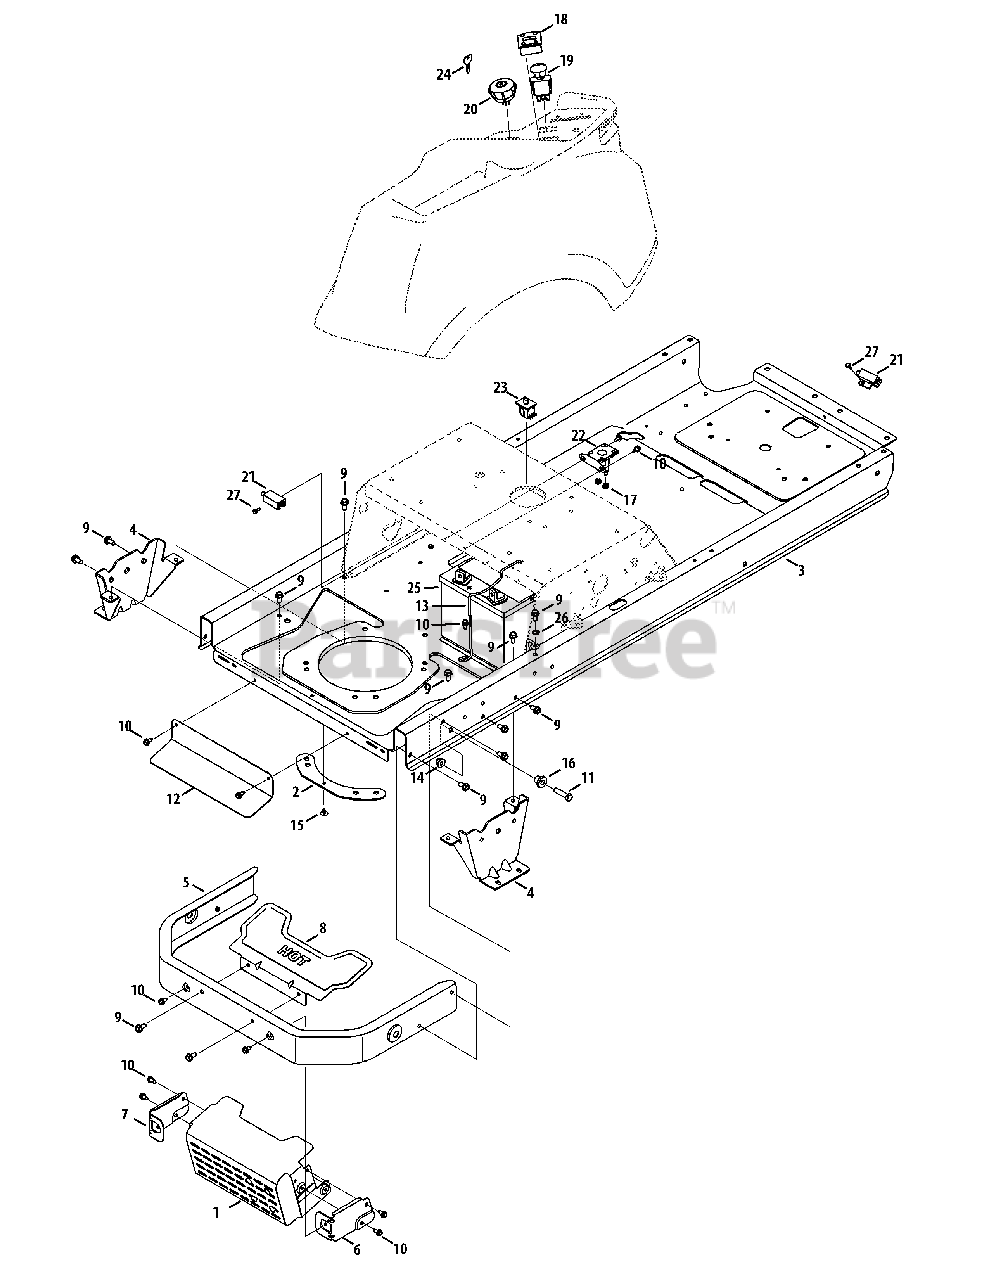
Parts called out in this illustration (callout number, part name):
1	Muffler Shield Assembly
2	Retainer Plate
3	Frame, RZT Yellow
3	Bracket, Transmission Mounting Front
3	Bracket, Spring Mounting
3	Plate Assembly, Steering RH
3	Plate Assembly, Steering LH
4	Transmission Mounting Bracket
5	Rear Bumper
6	Muffler Mounting Shield Bracket, RH
7	Muffler Mounting Shield Bracket, LH
8	Muffler Shield
9	Hex Washer Screw, 5/16-18 x .750
10	Hex Washer Screw, 1/4-20 x .625
11	Hex Screw, 3/8-16 x 1.25
12	Lower Heat Shield
14	Flange Lock Nut, 3/8-16
15	Clip, .250 Dia. x .500 LG
16	Shoulder Spacer, .38 x 1.0 x .70
17	Flange Lock Nut, 1/4-20
18	Hour Meter/Service Minder
19	Electric PTO Switch
20	Key Switch
21	Interlock Switch
22	Solenoid
23	Seat Switch
24	Key, Assembly
26	Lock Washer, 5/16
27	Shoulder Screw, #10-32 x .500
